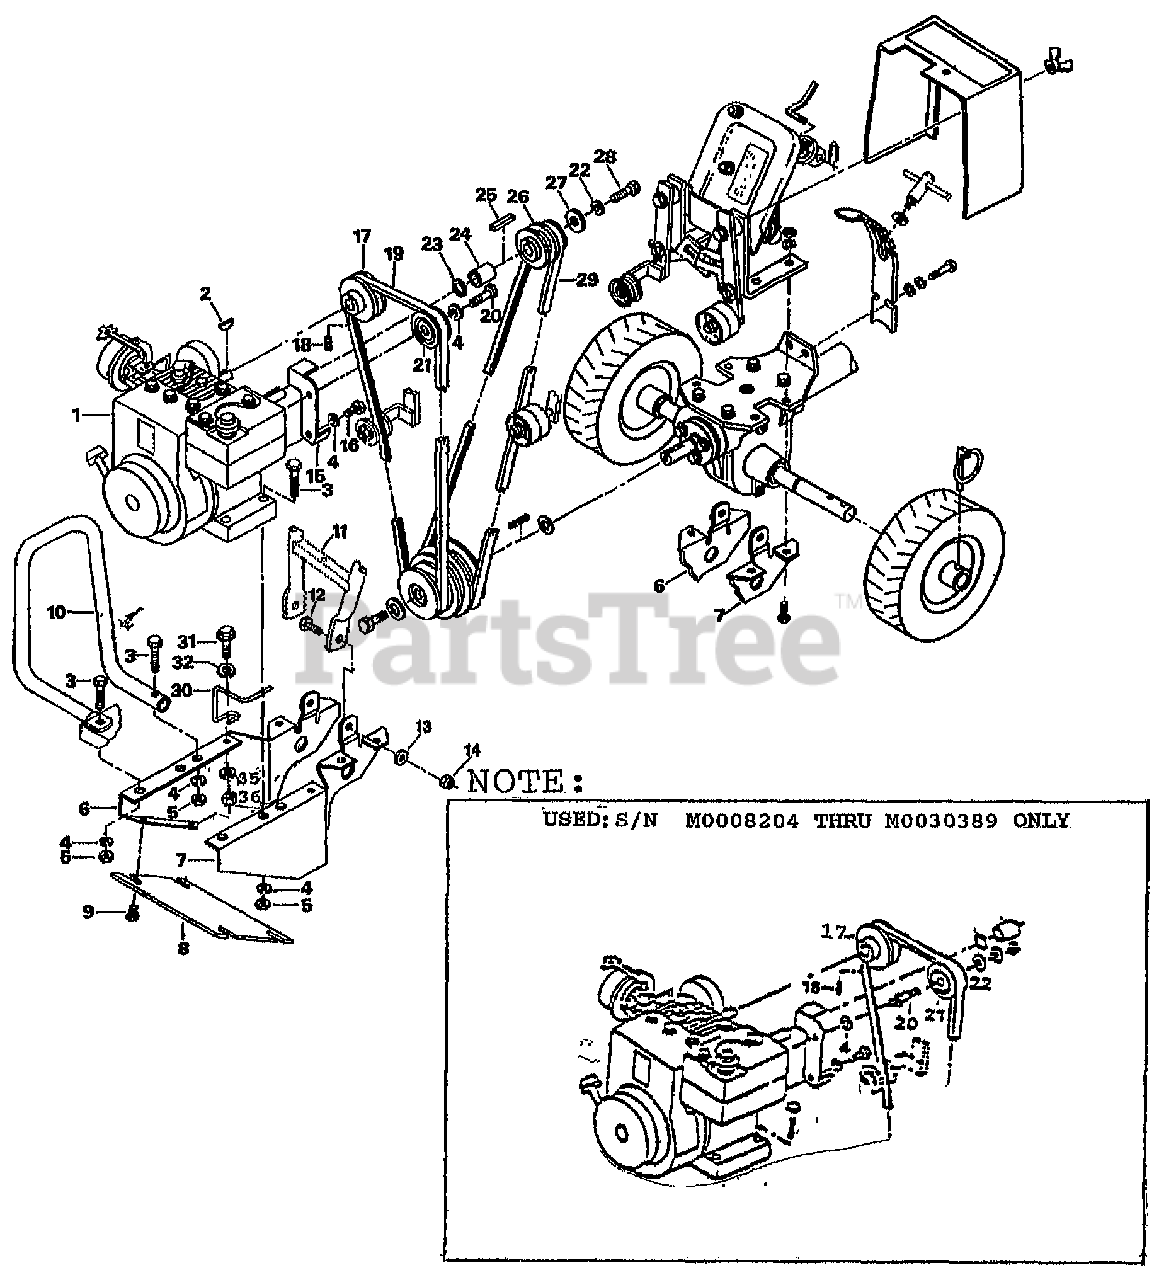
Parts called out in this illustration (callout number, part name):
1	TECUMSEH ENGINE - 3 1/2HP MODEL H36 TYPE 45593R
2	KEY-WOODRUFF #5 (Engine Pulley)
3	SCR-HH 5/16-18X1.5 G5 ZP
4	WASHER-LK .312 ZP
5	NUT-HEX 5/16-18 ZP
6	BRKT-ENG JR RT W/GUSSET
7	BRKT-ENG LT JR W/GUSSET
8	COVER-ENG BRKT PNT
9	SCR-HWH 1/4-20 X .5 STH (Used to attach Engine Bracket Cover to Bracket)
10	GUARD-CARBURETOR PNT
11	ASSM-HANDLEBAR
12	SCR-HH 3/8-16X1.0 G5 ZP (Handlebar Ass'y to Mounting Bracket)
13	WASHER-FLAT 3/8 SAE
14	NUT-LOCK 3/8-16 NYLON ZP
15	GUIDE-BELT REV PNT
16	SCR-HH 5/16-24X.50
17	PULLEY-REVERSE MACH (Used with S/N M43277 & later; repl. 50128; used with 18)
17	PULLEY-REVERSE MACH (used with 18)
18	SCR-SS 1/4-20 X .25 (For use with 50210 Pulley only; For old style, use 9564)
18	SCR M10-32X.25 (For old style pulley)
19	BELT-V (Reverse)
20	BOLT-HH 5/16-24 X 1.5 ZP (For Belt Guide Pulley; S/N 90390 & later)
20	STANDOFF 3/8-16 X 1.88 (Kit #1994)
21	IDLER-V-GROOVE (For S/N 30390 only & later)
21	KIT-REVERSE IDLER-JR2
22	WASHER-LK .375 @ DEPL
22	WASHER-FLAT 3/8 SAE
23	SHIM-1.0X.7656X.062
23	SHIM-1.0X.7656X.031
24	SPACER-.937X.755X.938
24	HEX NUT 3/8-16" (Kit #1994)
25	KEY-.188 SQ X 1.25 (Engine Pulley to Shaft)
26	PULLEY-ENG MACH
27	WASHER-1.25X.375X.1 ZP
28	CAP SCREW-HH 3/8-24 X 1 ZP
29	BELT-V (Forward)
30	GUIDE-BELT FWD
31	SCR-HWH 1/4-20 X .75 STH
32	WASHER-FLAT 1/4 SAE
35	WASHER-LK .25 ZP
36	NUT-HEX 1/4-20 ZP
